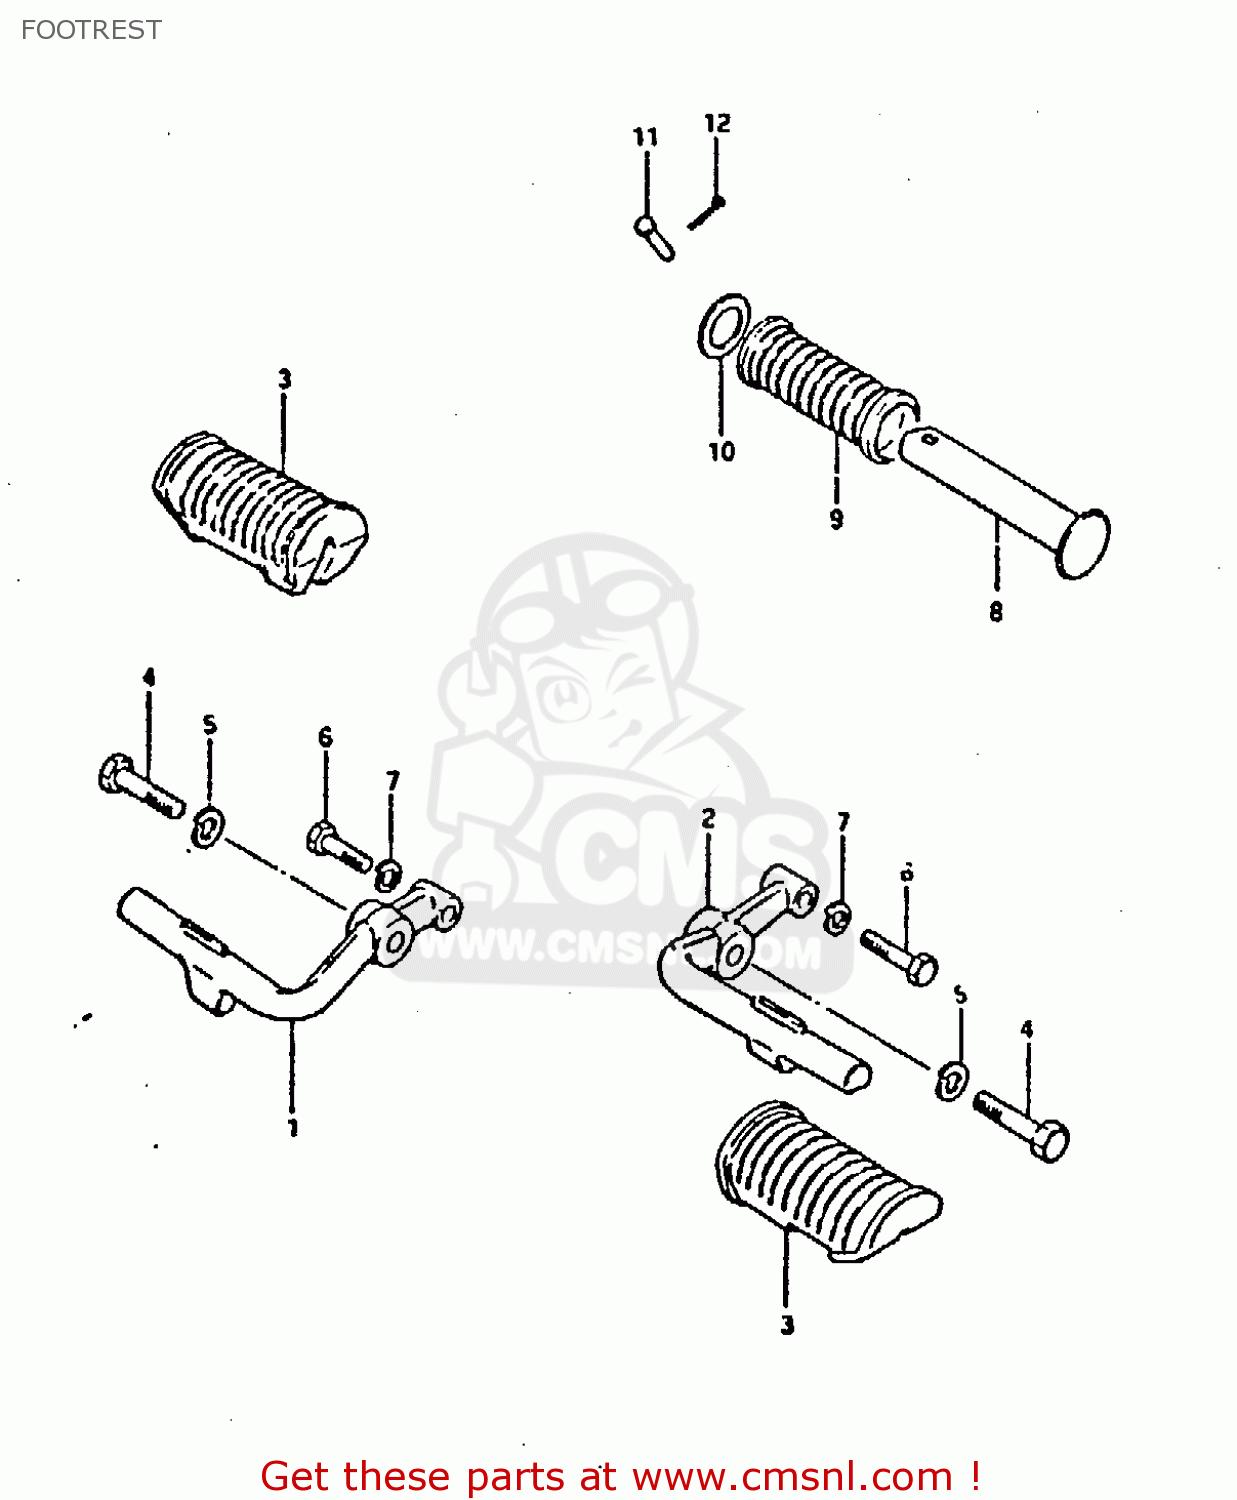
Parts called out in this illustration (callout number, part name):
1	BAR,FRONT FOOTREST,RIGHT
2	BAR,FRONT FOOTREST,LEFT
3	RUBBER,FR FOOTREST
4	BOLT
5	LOCK WASHER
6	BOLT 8X40
7	LOCK WASHER
8	BAR,PILLION FOOTREST
9	RUBBER,PILLION FOOTREST
10	WASHER (19.5X32X2)
11	PIN
12	PIN
